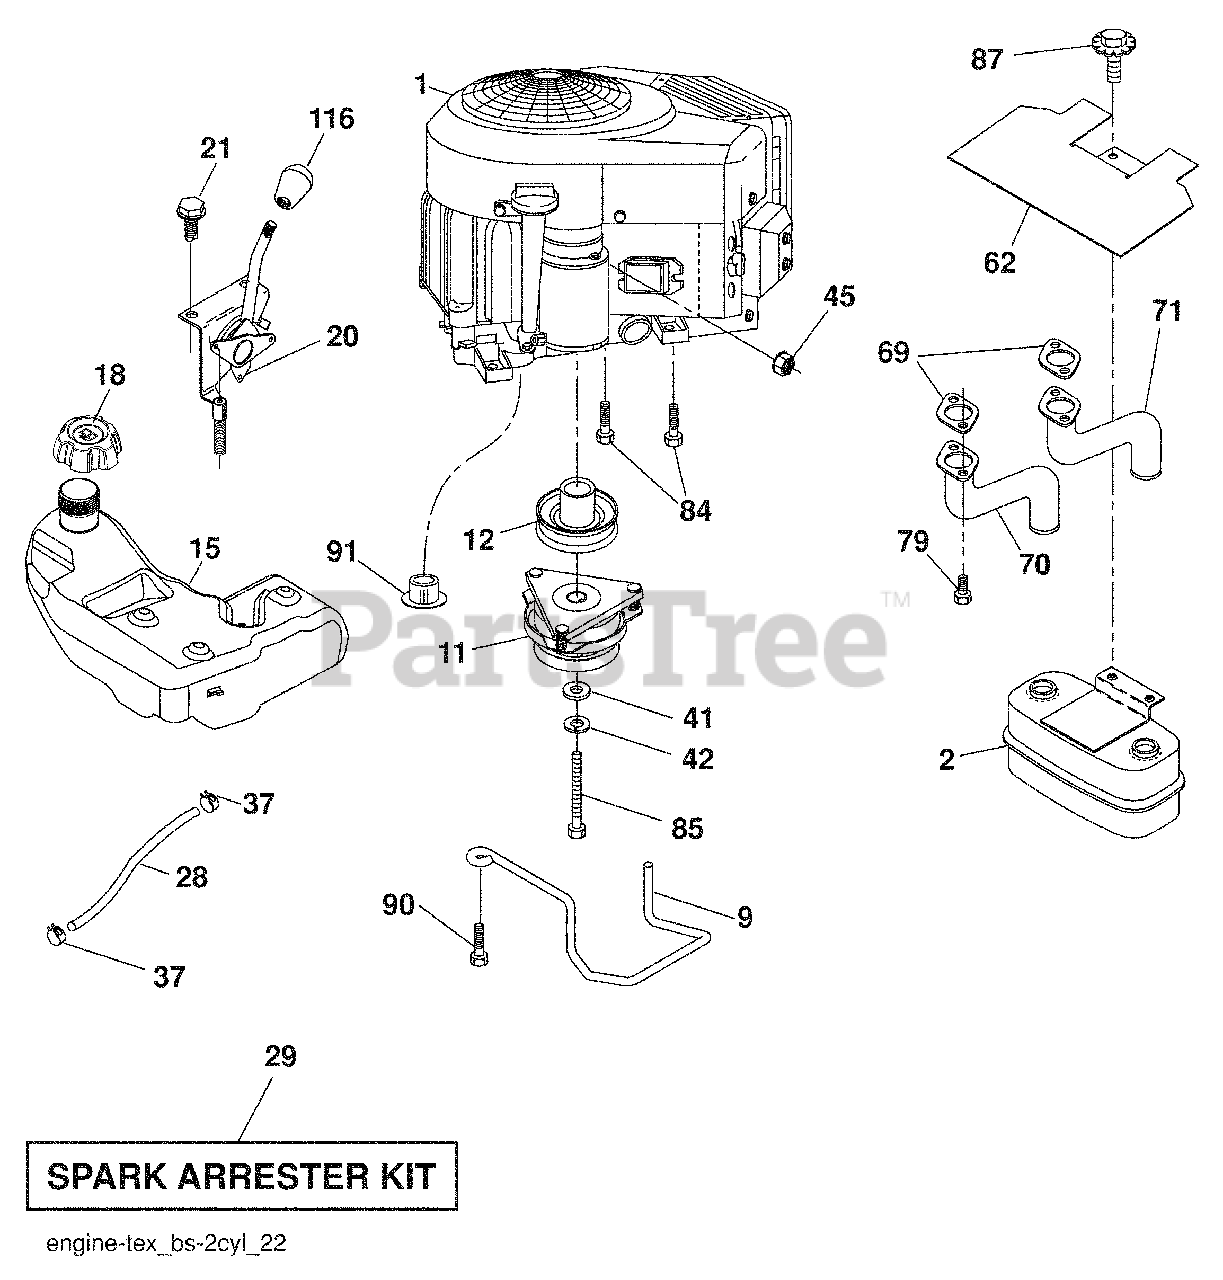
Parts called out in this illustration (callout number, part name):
9	Keeper Belt Engine
11	Clutch Electric
12	Pulley Engine
15	Tank Fuel
18	Cap Asm
20	Control Throttle
21	Screw #10 x .750 BOS Thread
28	Fuel Line
29	Spark Arrester Kit
37	Clamp Hose
41	Washer 1-1/2 OD x 15/32 ID x .250
42	Washer Lock 7/16
45	Nut Keps Hex 1/4-20 unc
62	Heat Shield
70	Tube Exhaust
71	Exhaust Tube
79	Screw Socket HP 5/16-18 x 1
84	Screw 3/8-16 x 1-1/4
85	Bolt Hex 7/16-20 x 4 x Gr. 5-1.5 Thr
87	Bolt 5/16-18 unc x 3/4 w/Sems
90	Screw 3/8-16 x 1
91	Bushing 1.375 OD
116	Knob Soft Touch
